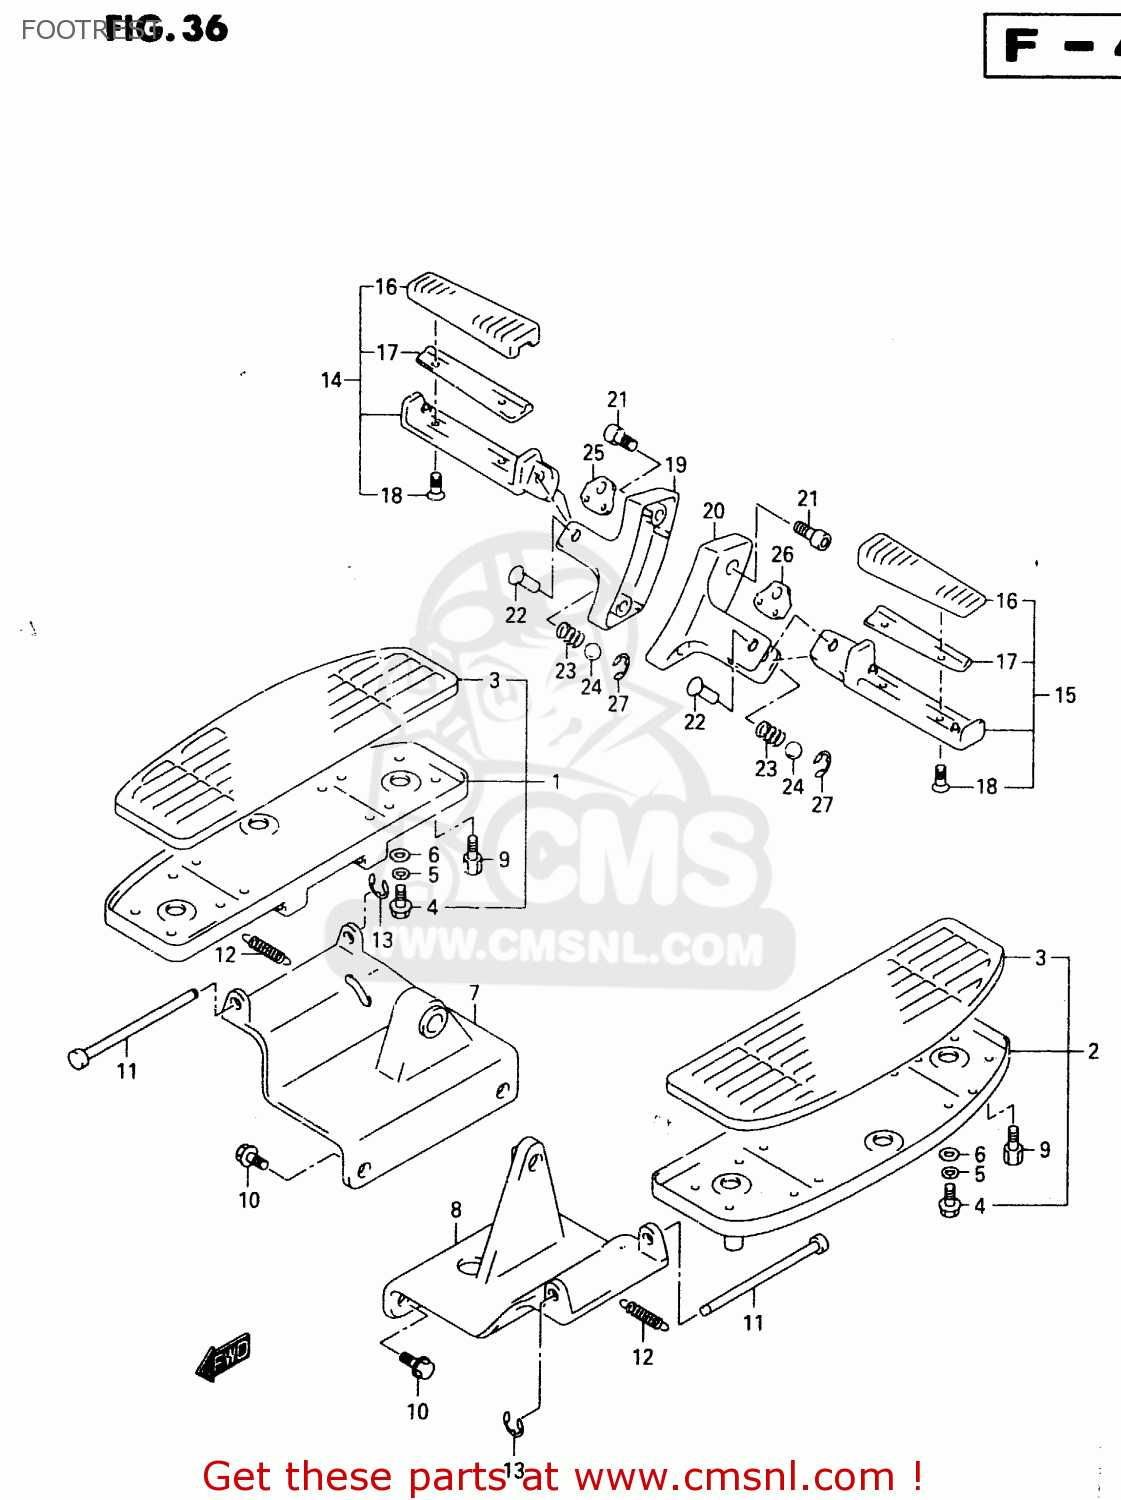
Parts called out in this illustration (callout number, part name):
1	FOOTREST ASSY,FR,R
2	FOOTREST ASSY,FR,L
3	RUBBER,FR FOOTREST
4	BOLT
5	WASHER (6.5X22X1.6)
6	CUSHION
7	BRACKET,FR FOOTREST,R
8	BRACKET,FR FOOTREST,L
9	BOLT,BANK SENSOR
10	BOLT
11	PIN,FR FOOTREST
12	SPRING
13	E.RING
14	FOOTREST ASSY,PILLION,R
15	FOOTREST ASSY,PILLION,L
16	RUBBER,PILLION FOOTREST
17	PLATE,RUBBER STOPPER
18	SCREW(5X16)
19	BRACKET,PILLION FOOTREST
20	BRACKET,PILLION FOOTREST
21	BOLT
22	PIN
23	SPRING
24	BALL
25	PLATE,PILLION FOOTREST,R
26	PLATE,PILLION FOOTREST,L
27	E.RING
